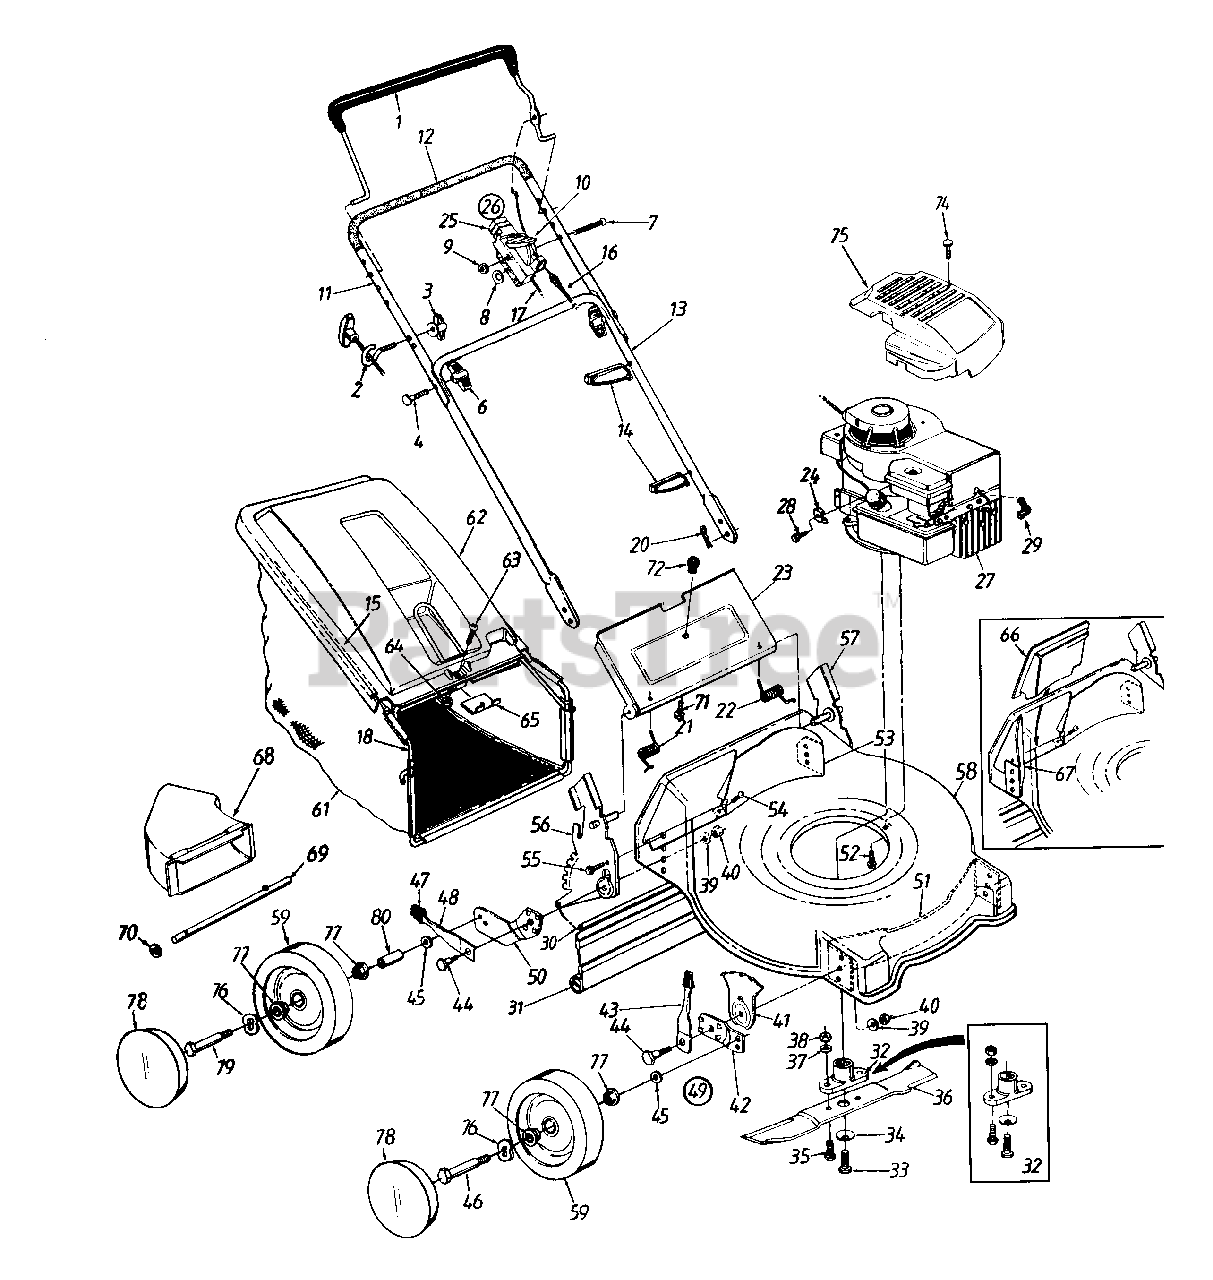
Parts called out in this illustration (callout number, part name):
1	Control Handle Ass'y.
3	Handle Knob 1/4-20 Thd.
4	Curved Hd. Bolt 5/16-18 x 2" Lg.
6	Hand Knob
7	Oval C-Sunk Mach. Scr.
8	Spr. Wash..66" I.D.
9	Hex L-Nut 1/4-20 Thd.
10	Throttle Lever
14	Cable Tie
16	Control Cable - 36"
17	Throttle Control Wire - 55"
21	Door Spring - R.H.
22	Door Spring - L.H.
25	Throttle Body
26	Throttle Box Comp.
27	Engine
28	Hex Wash. Hd. Scr. #10-32 x .62" Lg.
29	Spark Plug Boot
30	Wire Rod
31	Rear Flap
32	Blade Adapter Kit
33	Hex Bolt 3/8-24 x 1.5" Lg.
34	Bell-Wash..39" I.D.
35	Hex Bolt 3/8-24 x 1" Lg.
36	21" Mulching Blade
37	L-Wash. 3/8" I.D.
38	Hex Nut 3/8-24 Thd.
39	Bell-Wash. .39" I.D. x 1.38"
40	Hex Nut 3/8-16 Thd.
41	Height Adj. Plate
43	Spring Lever Ass'y. w/Knob
44	Shld. Bolt .5" Dia. x .357"
45	Bell-Wash. .38" I.D. x .88" O.D.
46	Front Axle Bolt
47	Spring Lever Knob
49	Height Adj. Ass'y. Comp. - R.H.
54	Torx Mach. AB-Tap Scr. 1/4 x .62" Lg.
55	Hex L-Wash. Hd. AB-Tap Scr. 1/4 x .62" Lg.
61	Grass Bag
62	Hard Top Cover
63	Pan Hd. Mach. Scr. 1/4-20 x .5" Lg.
64	Hex Nylon L-Nut 1/4-20 Thd.
68	Deflector
69	Rod
70	Push Speed Nut
71	Truss Scr. #10-24 x .38" Lg.
74	Hi-Lo Scr. #10 x 1.25" Lg.
75	XTL Grey Shroud
76	Wave Washer
77	Ball Bearings
78	Hub Cap
79	Rear Axle Bolt
80	Spacer
